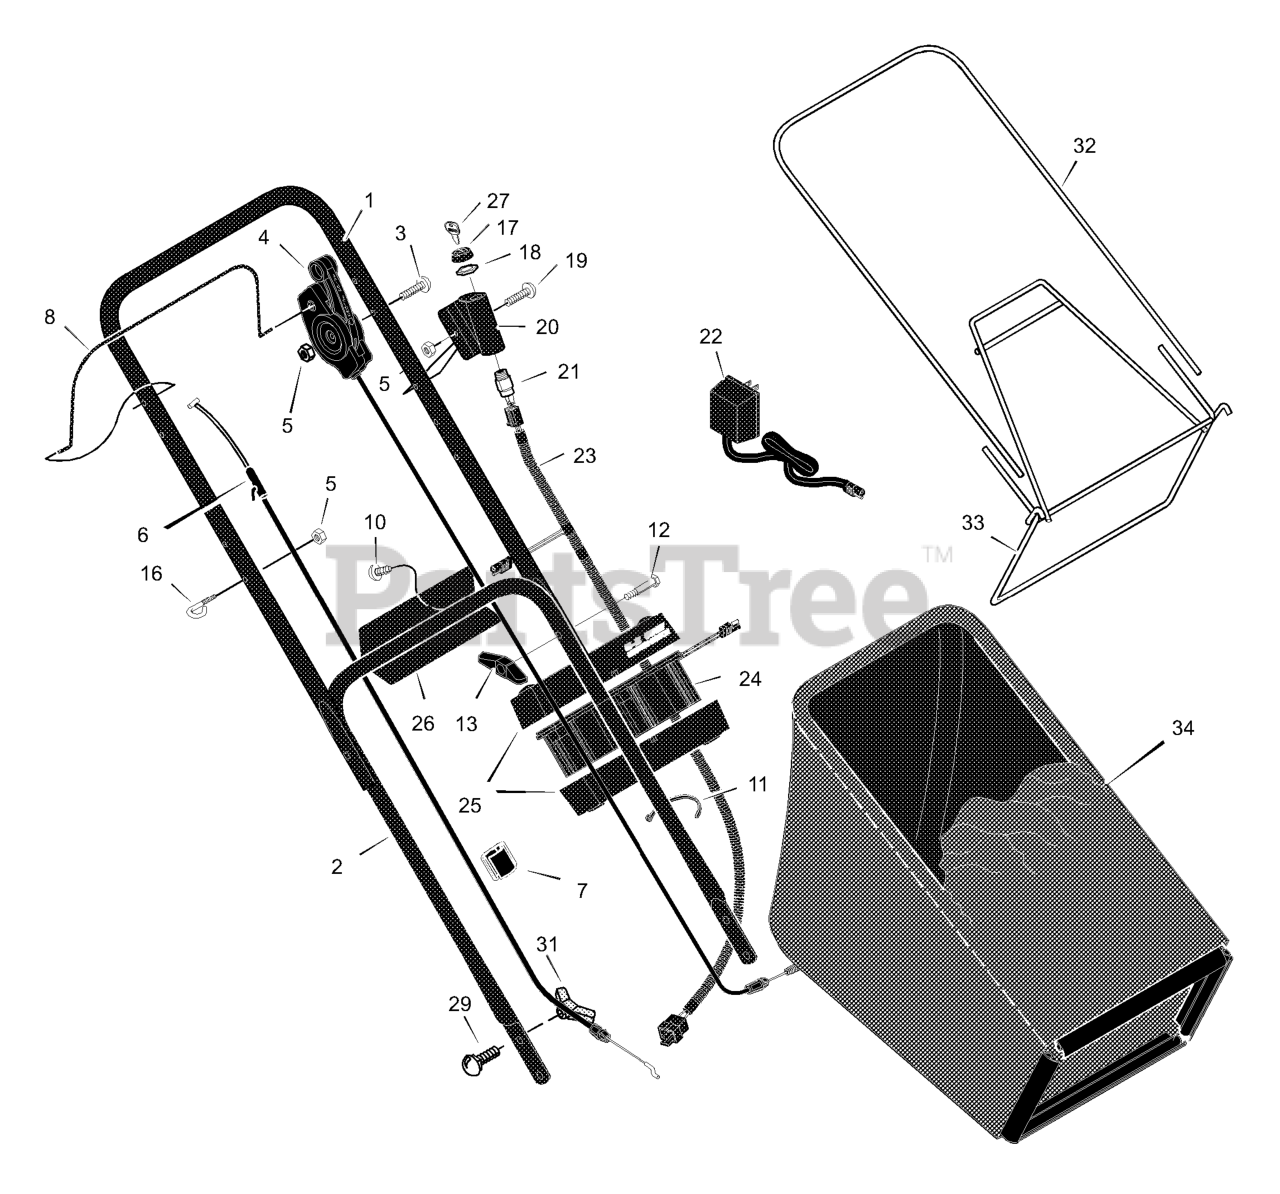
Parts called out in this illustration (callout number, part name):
1	Handle, Upper
2	Handle, Lower
4	Control, Drive
5	Locknut
6	Cable, Stop
7	Fastener, Cable
8	Lever, Stop
11	Fastener, Cable
13	Knob
16	Guide, Rope
17	Cap
18	Nut
20	Cover, Ignition
21	Switch Ignition & Key
22	Charger, Battery
23	Harness, Wiring
24	Battery
25	Case, Battery
26	Bracket, Battery
27	Key, Ignition
29	Bolt, Carriage
31	Knob, Plastic
32	Tube, Bag
33	Frame Assembly
34	Bag, Cloth
